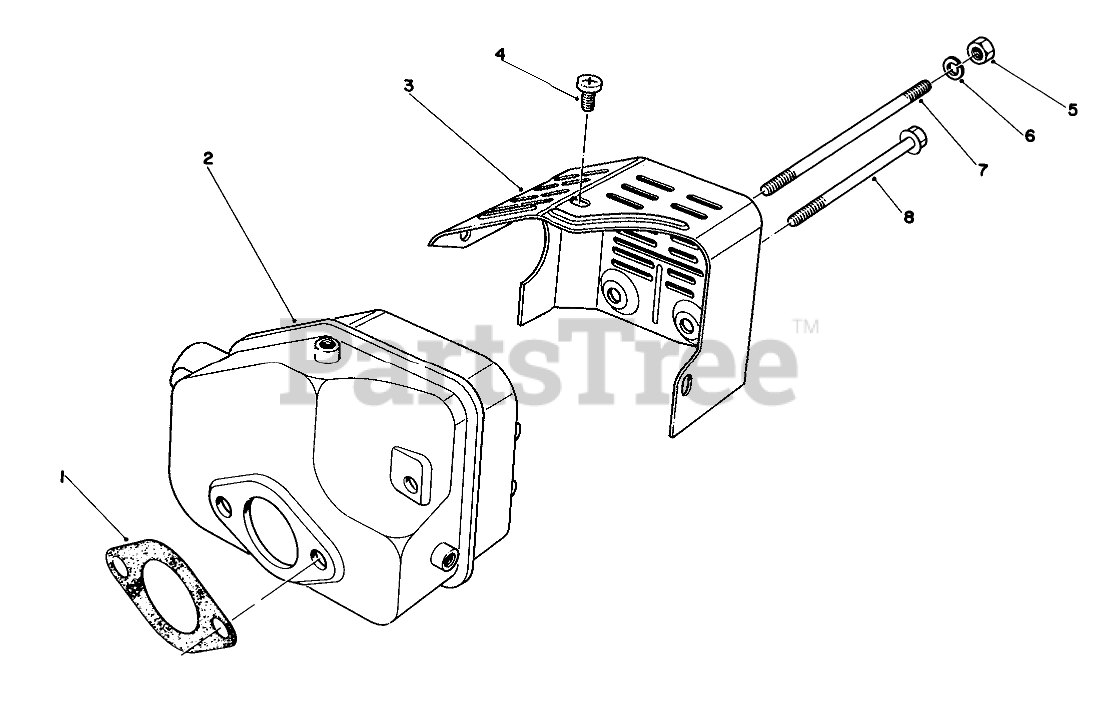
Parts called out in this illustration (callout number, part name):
1	GASKET
2	Muffler
3	COVER
4	SCREW
6	WASHER-LOCK
